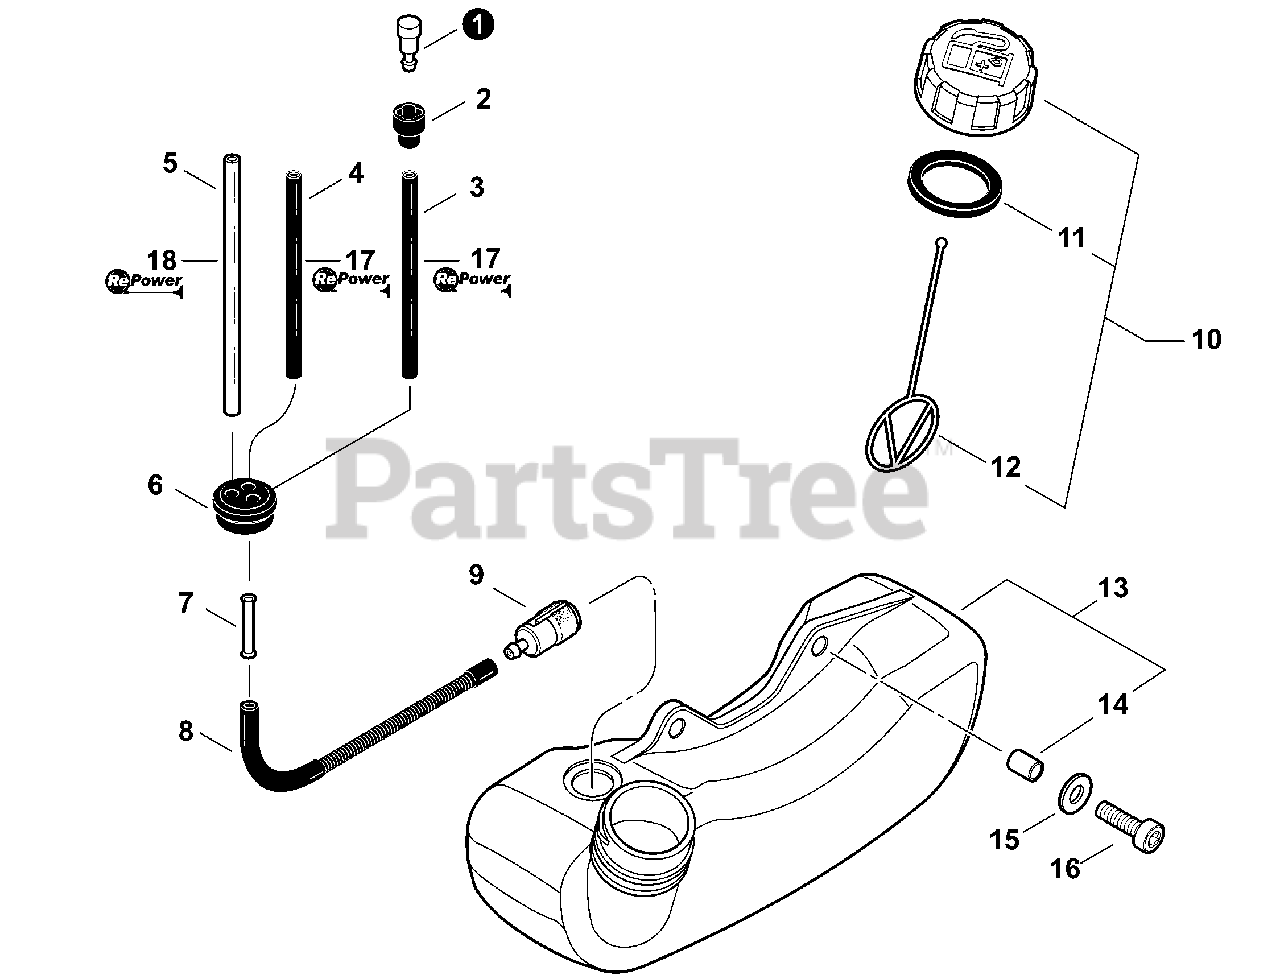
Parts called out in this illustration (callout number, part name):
1	VENT ASSY
2	HOLDER, VENT
3	PIPE, FUEL 3x-5x-70 BLACK
4	PIPE, FUEL 3×5×90 BLACK
5	PIPE, FUEL RETURN 3×6×90 MM CLEAR
6	GROMMET, FUEL Ø5
7	CONNECTOR, PIPE
8	PIPE, FUEL 3×7×100 FLEXIBLE
9	FILTER, FUEL
10	CAP ASSY, FUEL
11	GASKET, FUEL CAP
12	CONNECTOR, CAP L= 100 MM
13	TANK ASSY, FUEL
14	SPACER 6.2×7.8×6
15	WASHER 5.5×12×0.8
16	BOLT 5×16
17	BULK PIPE - 3×5 MM BLACK (4 PIECES×2 M)
18	BULK PIPE - 3×6 MM CLEAR (4 PIECES×2 M)
